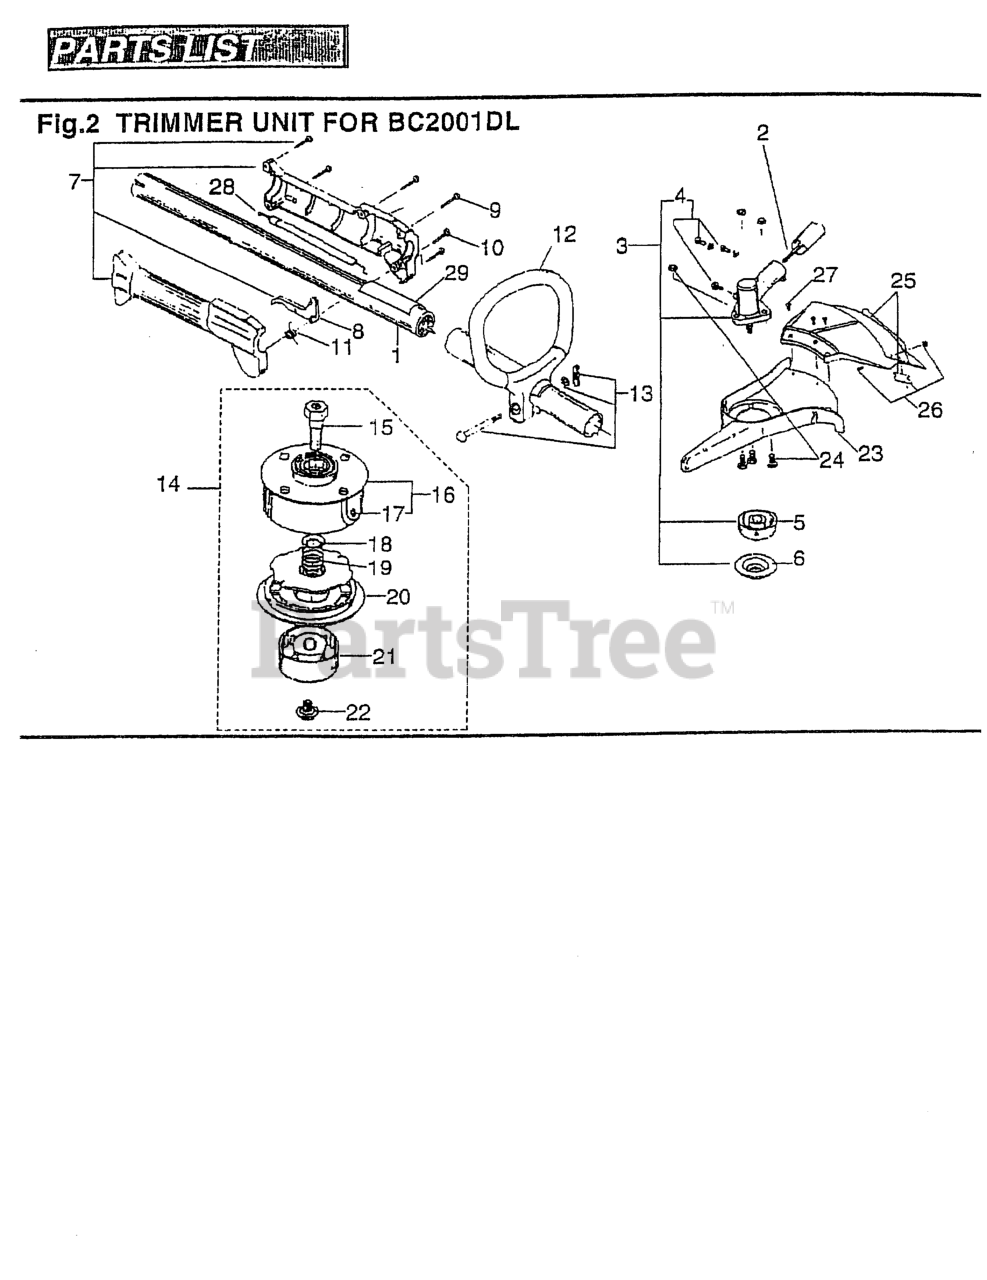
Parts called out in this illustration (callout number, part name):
1	PIPE ASSY (BC2001)(NLA)
2	SHAFT, FLEX (RLPS. 181773)
3	GEARCASE ASSEMBLY
4	HARDWARE, MOUNTING
5	HOLDER (U), BLADE DRIVER
6	HOLDER (L) (RPLS 613222)
8	LEVER, THROTTLE
9	SET SCREW, ANTI-ROTATION
11	SPRING, THROTTLE TRIGGER
14	UBT200 - CUTTING HEAD ASSY.
15	SHAFT
16	HOUSING, OUTER SPOOL
17	EYELET
18	WASHER
19	SPRING, INNER REEL
20	REEL, INNER
21	KNOB (USE 180814)
22	KNOB, BUMP HEAD (USE 180814)
23	MOUNT, GUARD
24	GUARD MOUNT HDWE SET
25	GUARD ASSEMBLY
26	BLADE ASSEMBLY
27	SCREW, GUARD MOUNT ASSY
28	CABLE ASSY, THROTTLE
29	LABEL, BC2001DL
